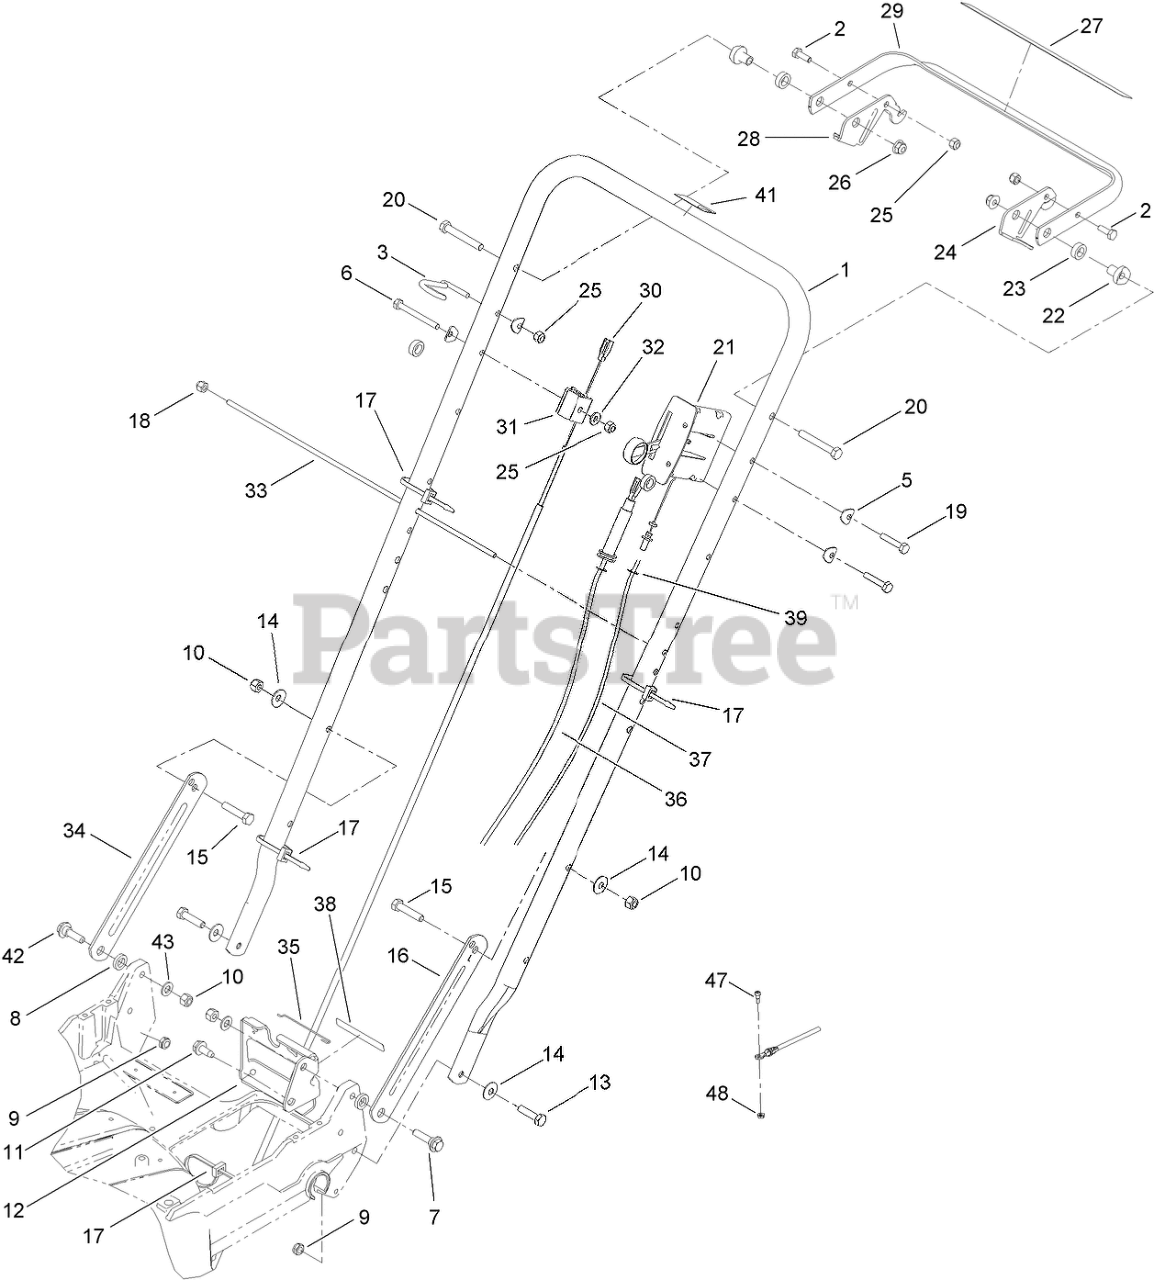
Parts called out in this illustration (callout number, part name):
2	SCREW-HH
3	GUIDE-ROPE
5	WASHER
6	SCREW-HH
7	SCREW-SHOULDER
8	SPACER
9	NUT-LOCK, NI
10	NUT-LOCK, NI
11	SCREW-HWHTF
12	BRACKET-ADJUSTMENT, TRACTION
13	SCREW-HH
14	WASHER-BELLEVILLE
15	SCREW-HH
16	LATCH-HANDLE, LH
17	TIE-CABLE
18	NUT-CAP
19	SCREW-HH
20	SCREW-HH
21	CONTROL-HEAD, THROTTLE
22	SPACER-SUPPORT
23	SPACER-NYLON
24	LEVER-CONTROL
25	NUT-LOCK, NI
26	NUT-HF, NI
27	Decal-Traction
28	LEVER-CONTROL
29	BAR-CONTROL
30	CABLE-BRAKE, CONTROL
31	SUPPORT-CABLE
32	WASHER-FLAT
33	ROD-SUPPORT, BAG
34	LATCH-HANDLE, RH
35	RETAINER-CABLE
36	CABLE-TRACTION
37	THROTTLE CABLE ASM
38	DECAL-POSITION, GEAR
39	E-RING
41	DECAL-PROTECTION, EAR
42	SCREW-SHOULDER
43	WASHER-PLAIN
47	SCREW-SHOULDER
48	NUT-LOCK, FLANGE
